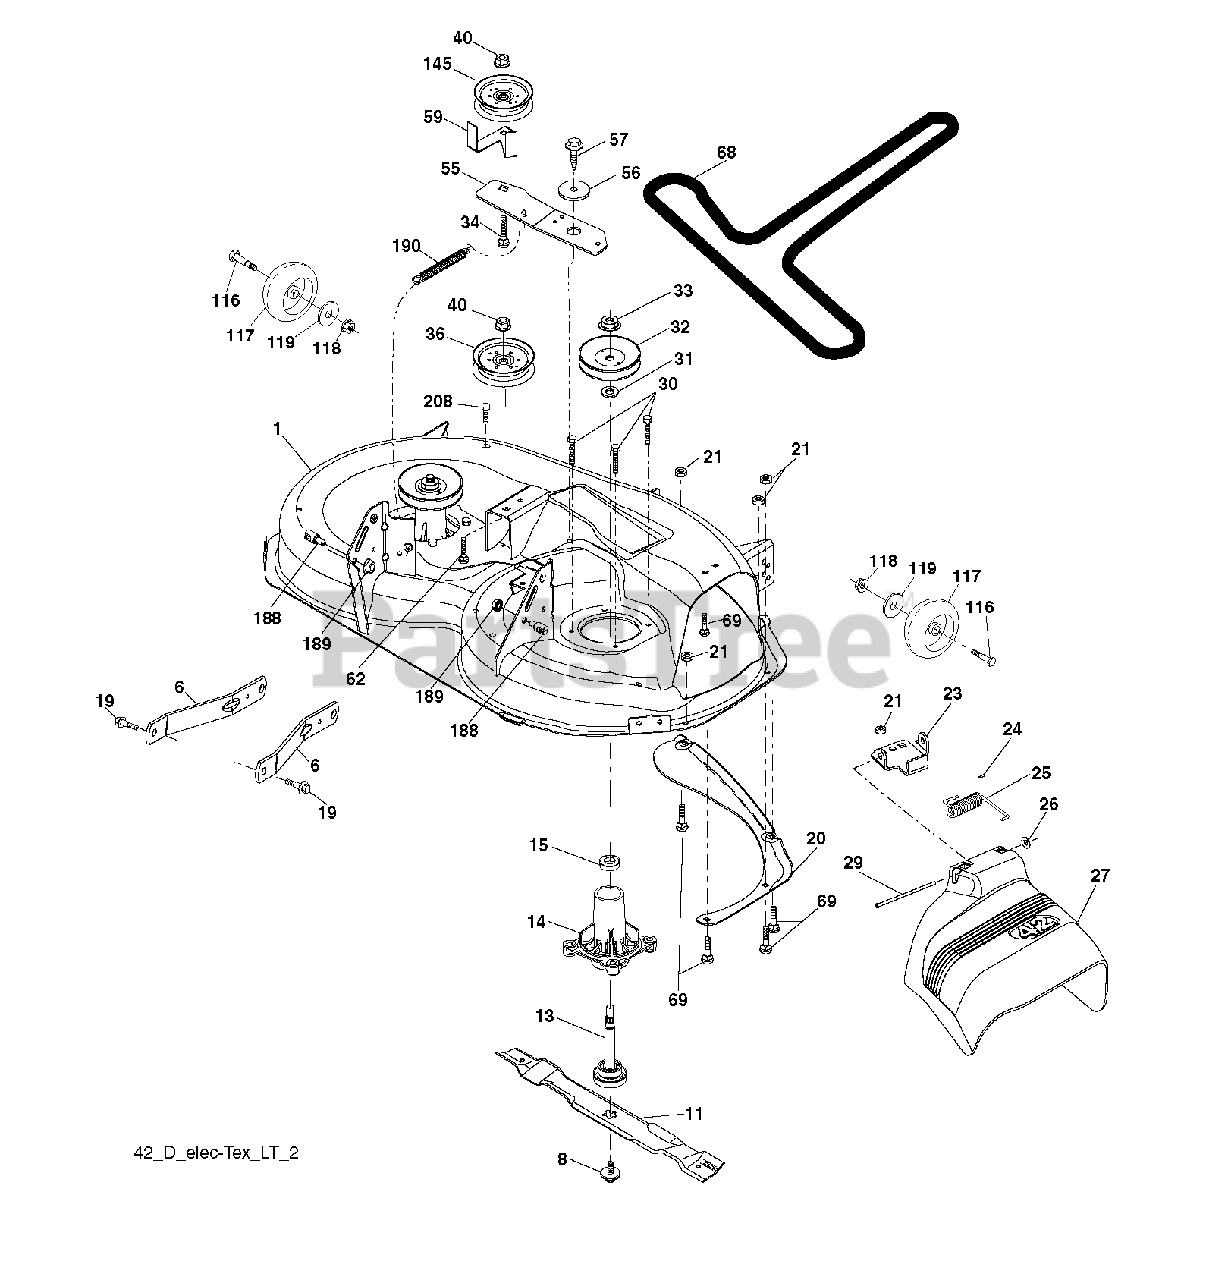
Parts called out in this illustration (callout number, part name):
1	DECK.WELDMENT.42"
6	ARM.SUSPENSION.MOWER.R
8	BOLT.WASHER.ASM.7/16-2
11	42" HI-LIFT BLADE
13	SHAFT.ASM.MDRL.N/GREASE.38
14	HOUSING.MANDREL.4PT.
19	BOLT.SHOULDER
20	BAFFLE.VORTEX
21	LOCKNUT
23	BRKT.DEFLECTOR.38"2005+
24	CAP-SLEEVE LT
25	SPRING.TORSION.DEFLECT
26	NUT PUSH M
27	SHIELD.DEFLECTOR.MOWER.42"BLAC
29	ROD.HINGE
30	SCREW, WASHER HEAD
31	WASHER.SPACER.MANDREL
32	PULLEY/MANDREL
33	NUT.FLANGE.LOCK.TOP
34	BOLT.3/8-16X1.50
36	PULLEY.IDLER.2006
40	NUT LOCK FLG 3/8-16 UNC
55	IDLER.ARM.42"
56	SPACER.RETAINER
57	SCREW 3/8-16X1
59	GUARD, BELT
68	BELT V SECONDARY
69	BOLT
116	BOLT M
117	WHEEL.GAGE.HALF.SPOKED
118	LOCKNUT
119	WASHER
145	PULLEY.IDLER.48"PRIMARY
188	STUD.FASTNER.W/ANTI-ROTATE
189	NUT LOCK HEX FLANGE 5/16-18
190	SPRING.MOWER.DRIVE.ELECTRIC
208	SCREW 3/8-16X1/2
